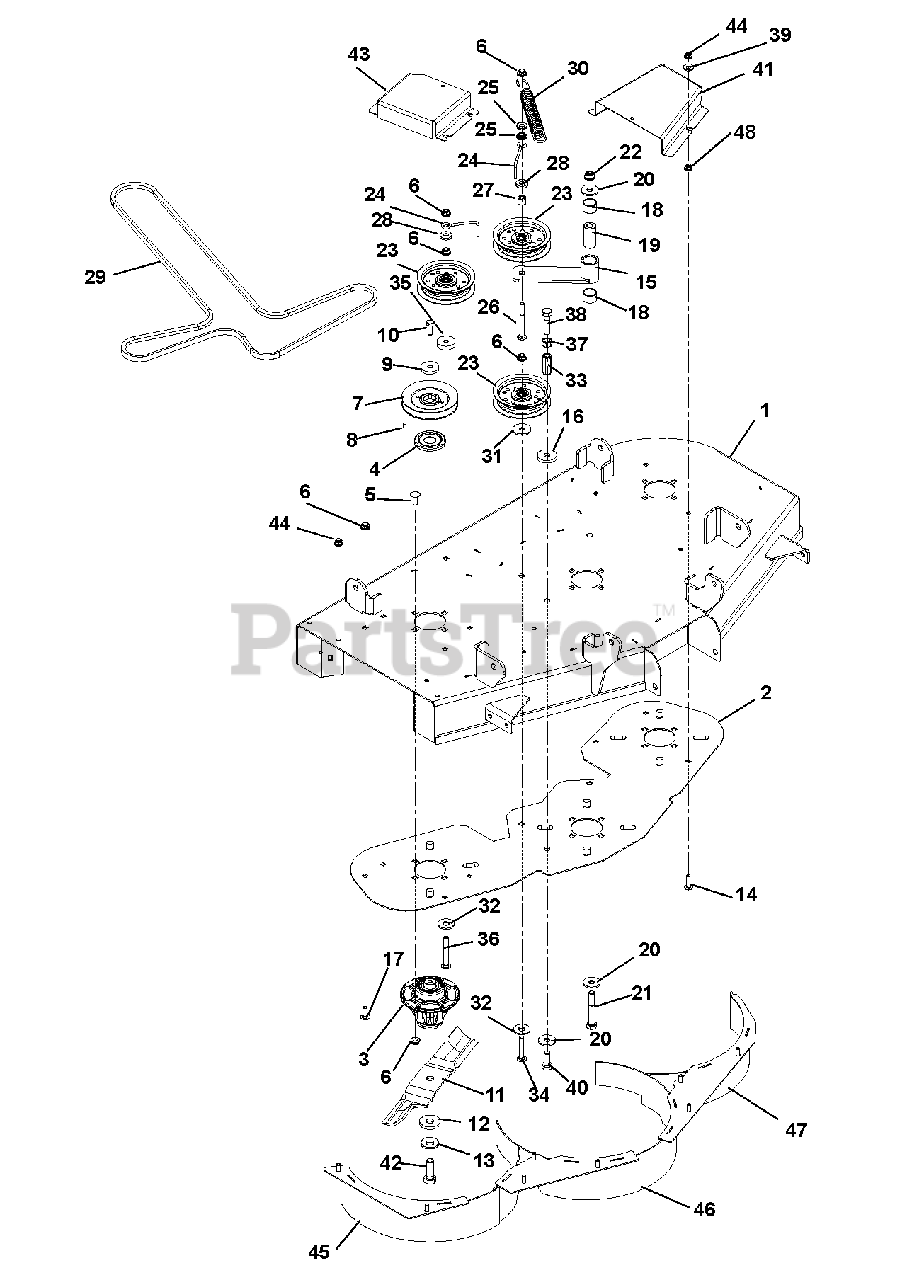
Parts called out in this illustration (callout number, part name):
1	XL – Deck Kit CE
2	Doubler Plate, 42" Deck
3	Spindle Assembly
4	Dust Cap
5	Bolt, Round Head Square Neck .38-16 x 1.25 Grade 5
6	Nut, .38-16 Nyloc Flange
7	Sheave, 4.75 Diameter A-Section
8	Key, Square .25 x .38 x
9	Washer, Flat Steel .406 x 1.50 x .245
10	Bolt, Hex .38-16 x 1.00 EP30
11	Blade, Mulch 14.50"
12	Washer, Flat .640 x 1.75 x .250
13	Washer, Bellville .63 x 1.625 x .14
14	Bolt, Serrated Hex Flange Washer Head .312-18 x .50
15	Idler Arm
16	Washer, Flat Steel .515 x 1.625 x .250 YZ
17	Bolt, Round Head Square Neck .38-16 x 1.00 Grade 5
18	Bearing, 1.00 x 1.12 x .75
19	Bushing, Spacer .505/.500 x .999/.996 x 2.05/2.03 Promaster
20	Washer, Flat Steel .511 x 1.441 x .125
21	Bolt, Hex .50-13 x 3.25 Grade 5
22	Nut .50-13 Nyloc Flange
23	Assembly, Idler 4"
24	Belt Finger
25	Bushing, Flange .406 x .88 x .270 x .140
26	Bolt, Round Head Square Neck .38-16 x 3.50 Grade 5
27	Bushing, Sleeve .391 x .688 x .52
28	Washer, Flat Steel .406 x 1.00 x .188
29	Belt, HA 127.12 Wrapped
30	Extension Spring
31	Washer, Flat Steel .39 x 1.5 x .125
32	Plate, Idler Mount Reinforcement
33	Nut, Coupling .50-13 x 1.75
34	Bolt, Round Head Square Neck .38-16 x 2.25 Grade 5
35	Spacer, .39 x 1.50 x .380
36	Bolt, Round Head Square Neck .38-16 x 3.0 Grade 5
37	Nut, Hex .50-13
38	Bolt, Hex .50-13 x 2.00 Grade 5
39	Nut, Push .312
40	Bolt, Hex .50-13 x 1.25 Grade 5
41	Belt Cover, Left
42	Bolt, Hex .62-18 x 1.75 Grade 8
43	Belt Cover, Right
44	Nut, .31-18 Nyloc Flange
45	Weldment, 42 Baffle Right Hand
46	Weldment, 42 Mulch Baffle (CTR)
47	Weldment, 42 Mulch Baffle Left Hand
48	Nut-Jam .312-18 (Serial Number 6059 +)
